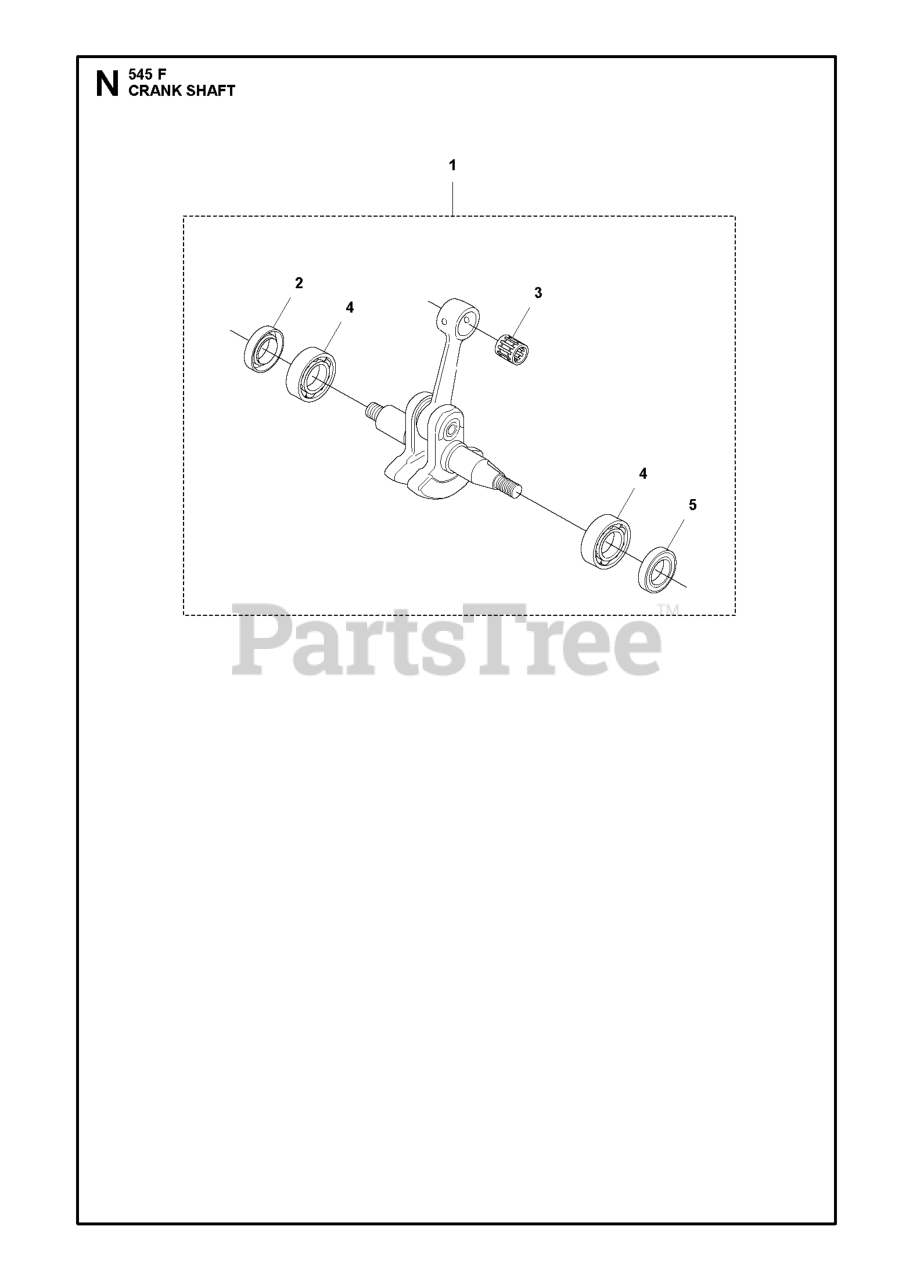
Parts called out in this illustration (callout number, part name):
2	RADIAL SEAL
3	SUPPORT BUSHING
4	BALL BEARING
